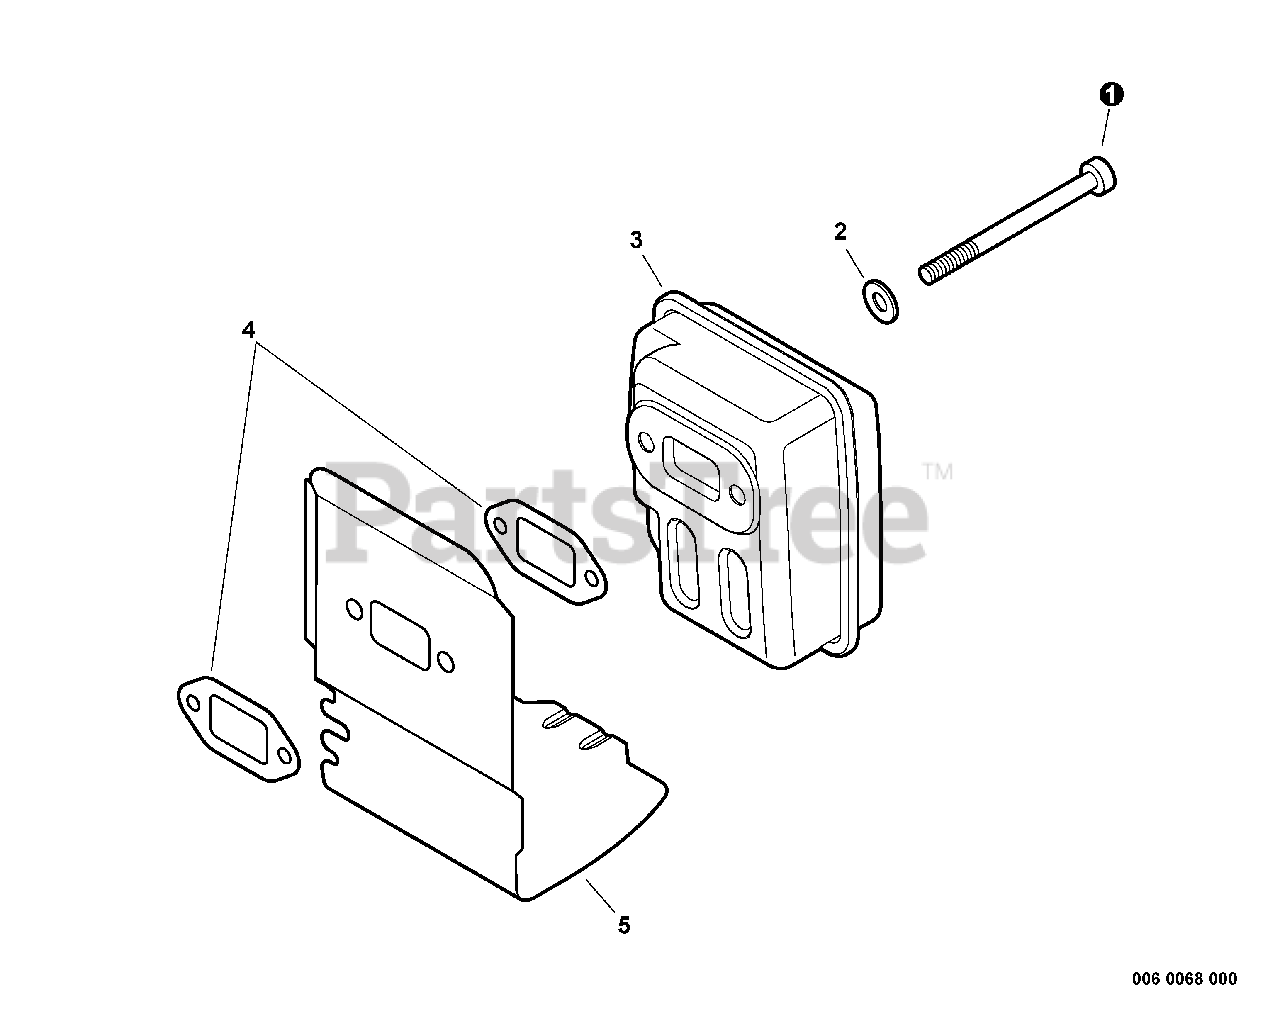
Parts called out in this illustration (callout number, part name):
1	BOLT 5×55
2	WASHER, FLAT 5.5×10×0.8
3	MUFFLER
4	GASKET, EXHAUST
5	HEAT SHIELD, EXHAUST
